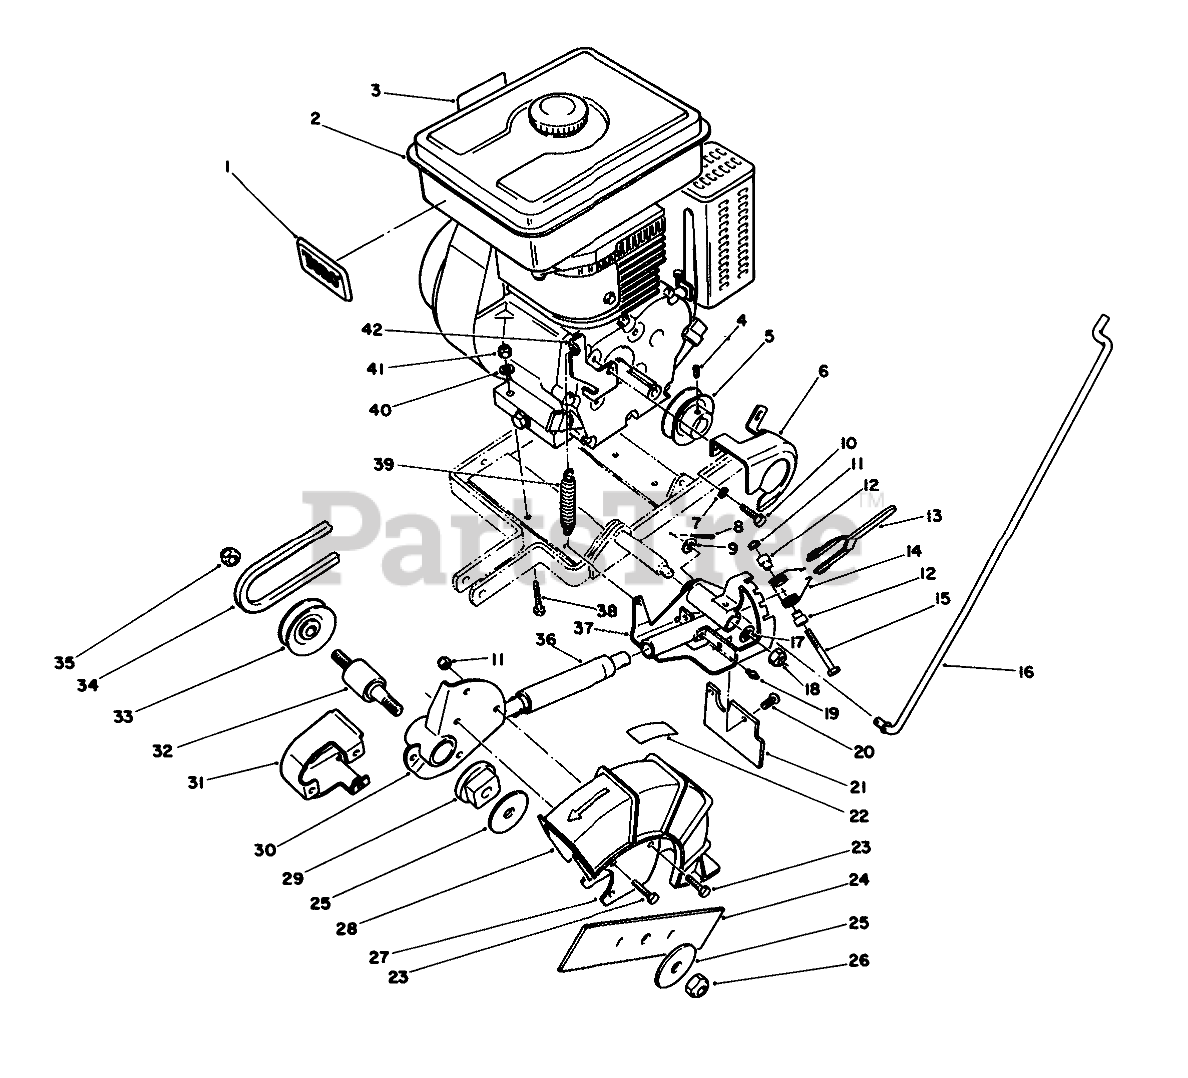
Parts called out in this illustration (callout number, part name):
1	TORO LOGO PLT
3	Decal-Instruction
4	SCREW-SET
5	PULLEY (3.5 HP)
6	ENG. PULLEY GUARD
7	WASHER-LOCK
8	PIN-COTTER
9	WASHER-FLAT
10	SCREW-HH
11	NUT-LOCK, NI
12	SPACER-PIVOT LEVER
13	LEVER WA
14	TORSION SPRING
15	SCREW-HH
16	LOWER CONTROL ROD
17	WASHER-PLAIN
18	NUT-LOCK, NI
19	FITTING-GREASE
20	PANEL FASTENER
21	RUBBER GUARD
22	Decal-Warning
23	SCREW-HWHTF
24	10" EDGER BLADE B
25	WASHER-LARGE
26	NUT-HEX
27	GUARD PLATE
28	Guard-Blade (Incl. Ref. #22)
29	BRG SHIELD
30	HUB ASM
31	PULLEY GUARD WA
32	SPINDLE ASM
33	PULLEY
34	V-BELT
35	NUT-LOCK, NI
36	SPRING & BELLOW ASM
37	PIVOT ARM WELDMENT B
38	SCREW-HH
39	EXT. SPRING
40	WASHER-PLAIN
41	NUT-LOCK, NI
42	SPRING BRKT R
